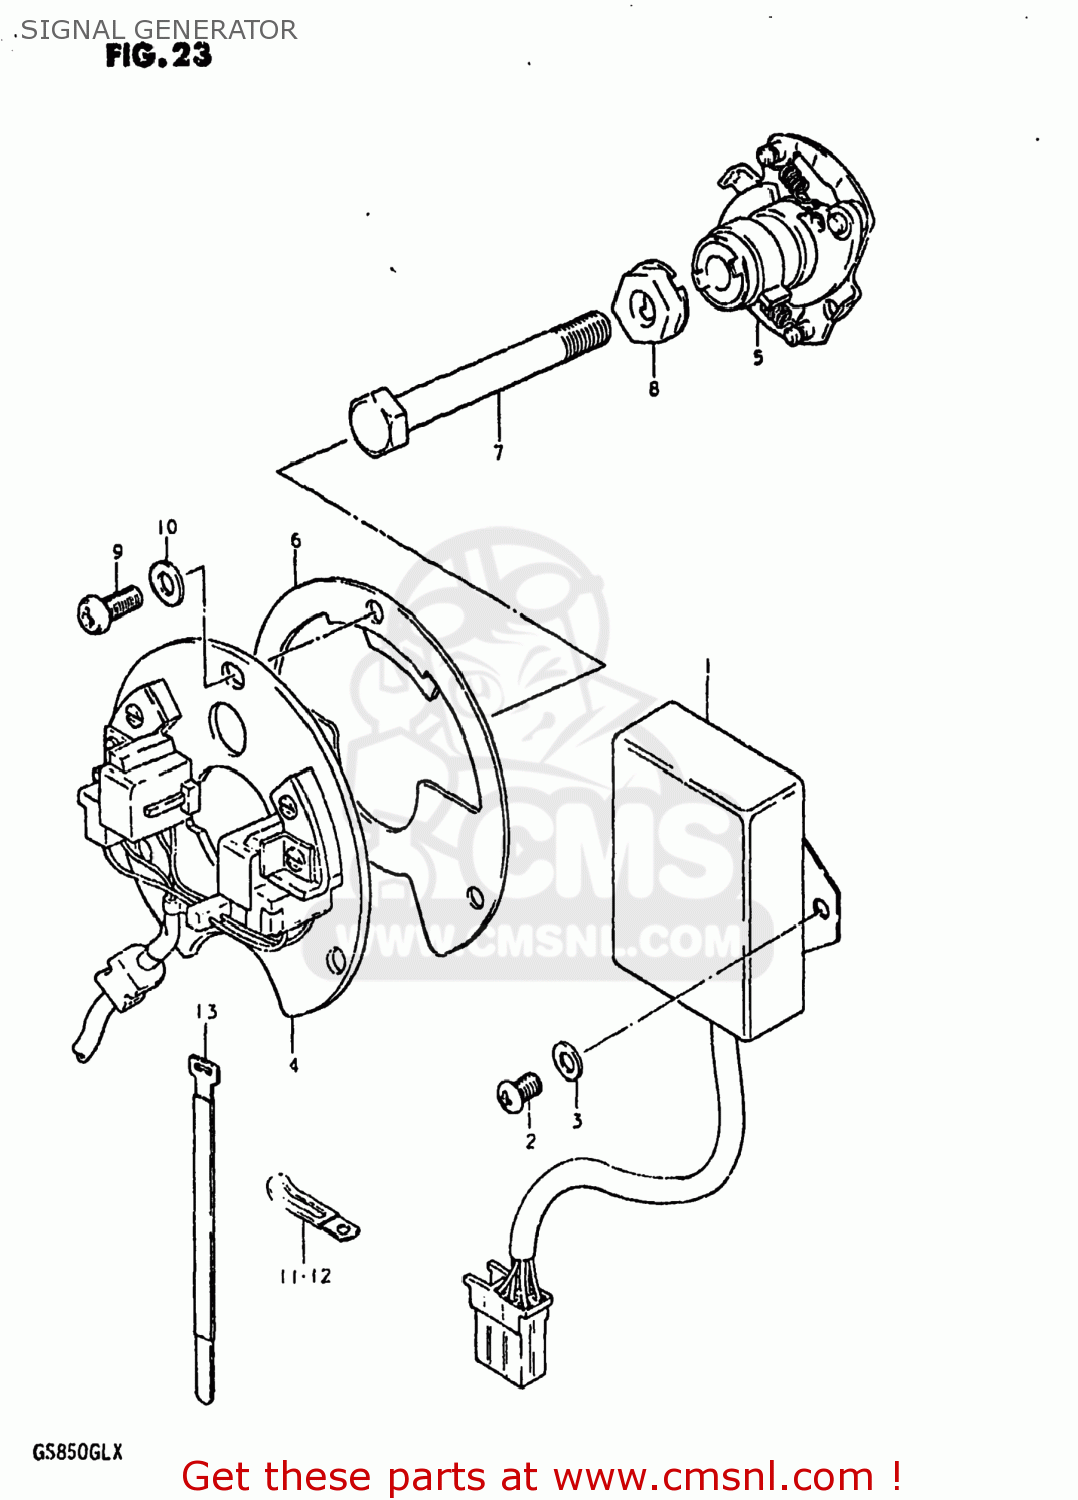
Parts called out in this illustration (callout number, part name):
1	IGNITER UNIT
2	SCREW
3	WASHER
4	SIGNAL GENERATOR ASSEMBLY
5	GOVERNOR ASSEMBLY
6	PLATE,TIMING
7	BOLT
8	WASHER
9	SCREW(5X12)
10	WASHER
11	CLAMP L:35
12	CLAMP
13	CLAMP
